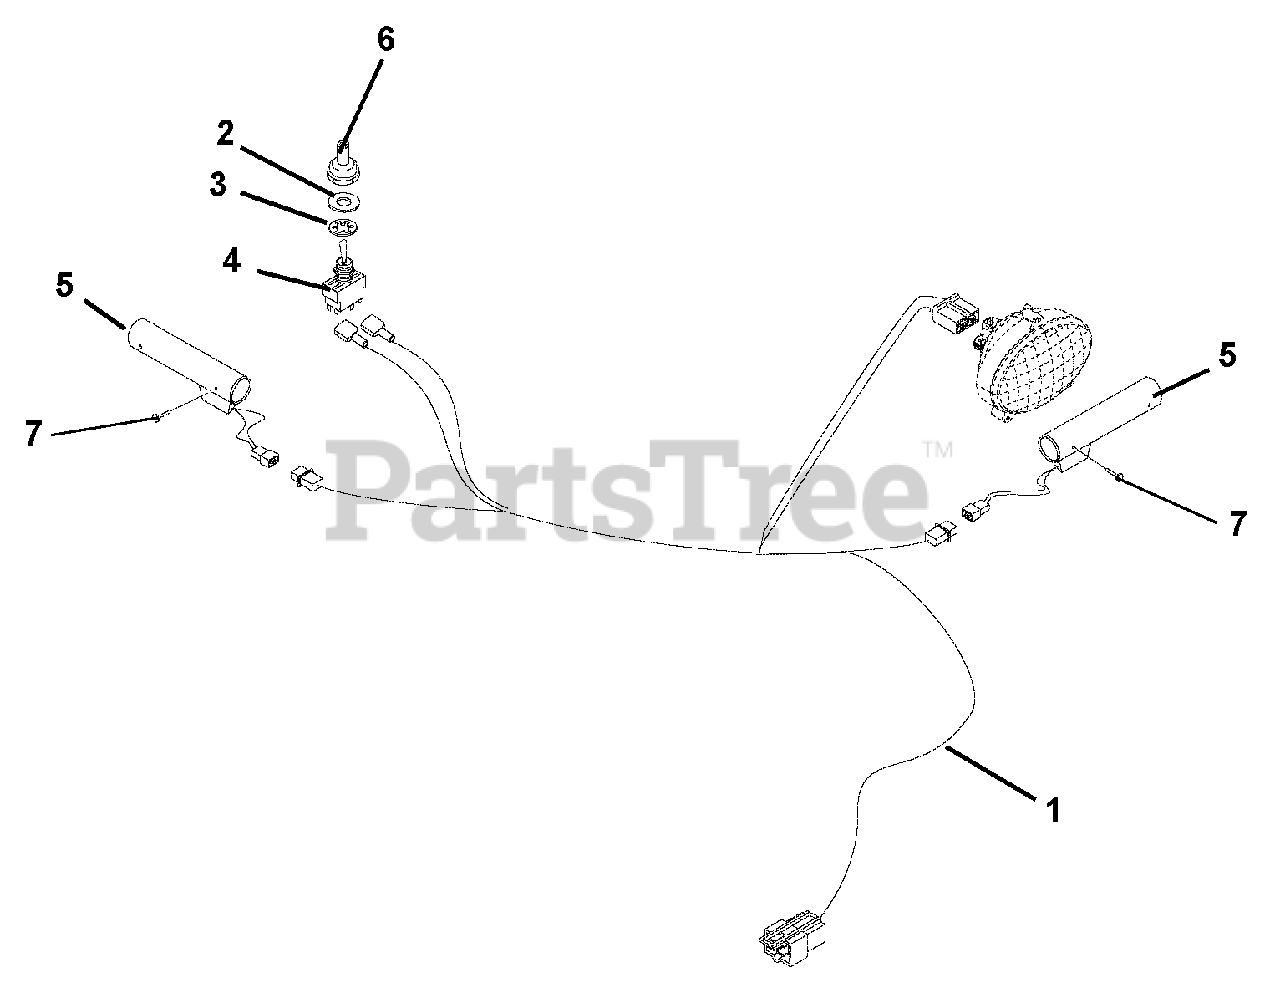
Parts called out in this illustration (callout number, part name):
1	Harness, Wiring-Light and Handwarmer
2	Washer, Flat Steel .51 x .88 x .024
3	Washer, Locking Internal .56 x .04
4	Switch, On/Off Hand Warmer
5	Hand Warmer with Terminal (Recommend Fast Drying Epoxy for Installation)
6	Boot, Switch (Optional)
7	Rivet, Pop #43 .125 x .313
